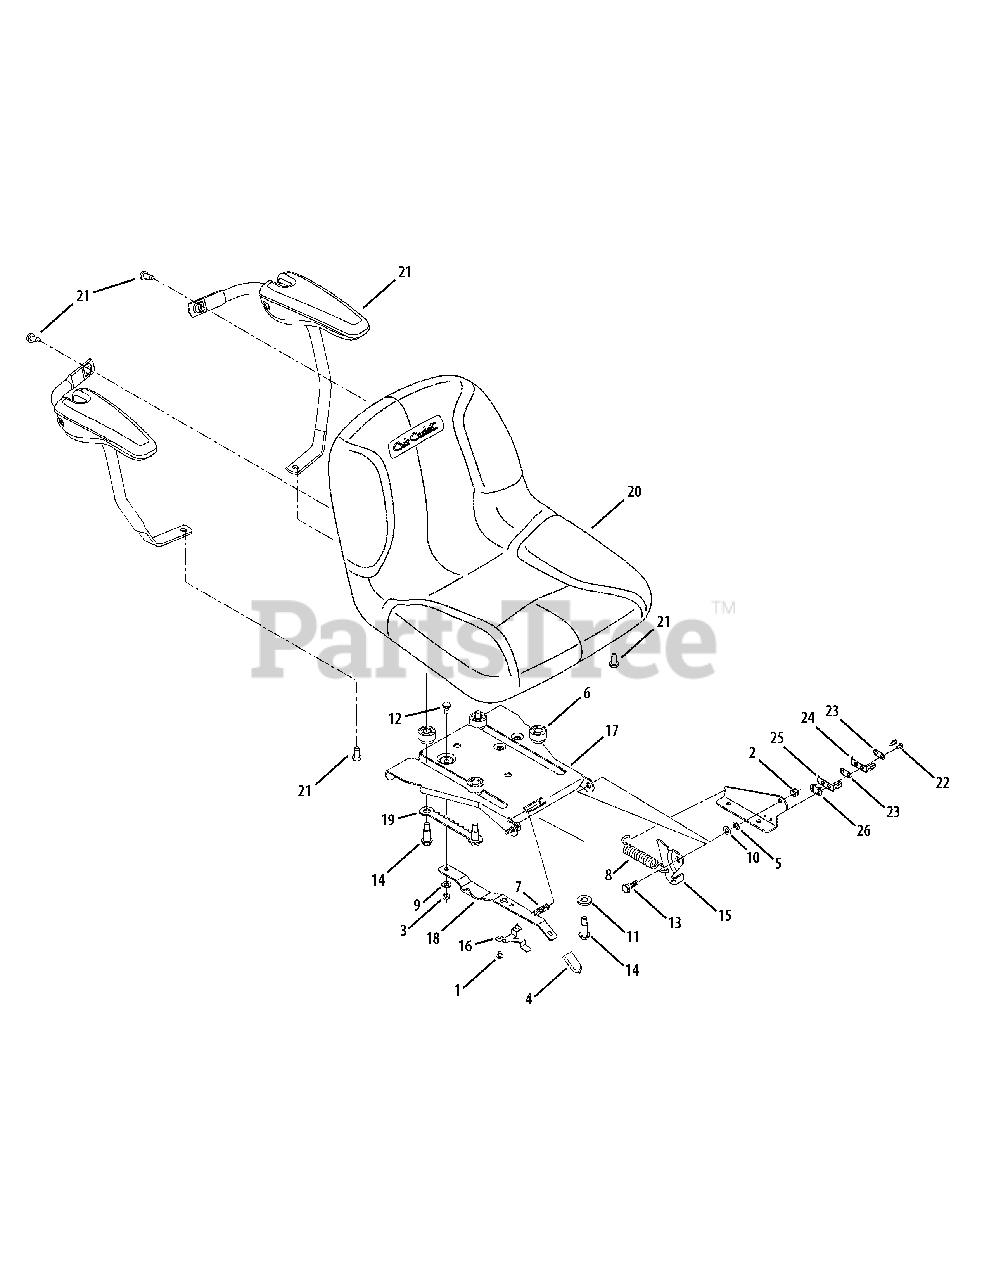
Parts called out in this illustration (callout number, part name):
1	Screw, #10-16, 0.375
2	Nut, Nylon Lock, 5/16-18, Gr5
3	Nut, Nylon Lock, 1/4-20 GrF
4	Grip, Seat, Adjustment
5	Nut, Speed, .3125 ID
6	Spacer, Seat, Adjustment
7	Spring, Compression .41 x 1.50
8	Spring, Extension, .80 Dia x 4.6
9	Washer, Flat, .344 x ..620 x .033
10	Washer, Flat, .340 x .872 x .060
11	Washer, Flat, .531 x 1.062 x .134
12	Screw, Shlder, .340 x .285, 1/4-20
13	Shoulder, Screw .437 x .286 Lg
14	Screw, Shoulder, .50 x.925, 3/8-16
15	LH Bracket, Seat Lift
16	Stop, Seat, Adjustment
19	Selector, Seat, Adjustment
20	Seat, Cub Cadet, High Back
21	Arm Rest Kit
22	Screw, #8-18 x .50
23	Plate, Insulator
24	Spring Switch, Outer
25	Spring Switch, Inner
26	Plate, Insulator Boss
